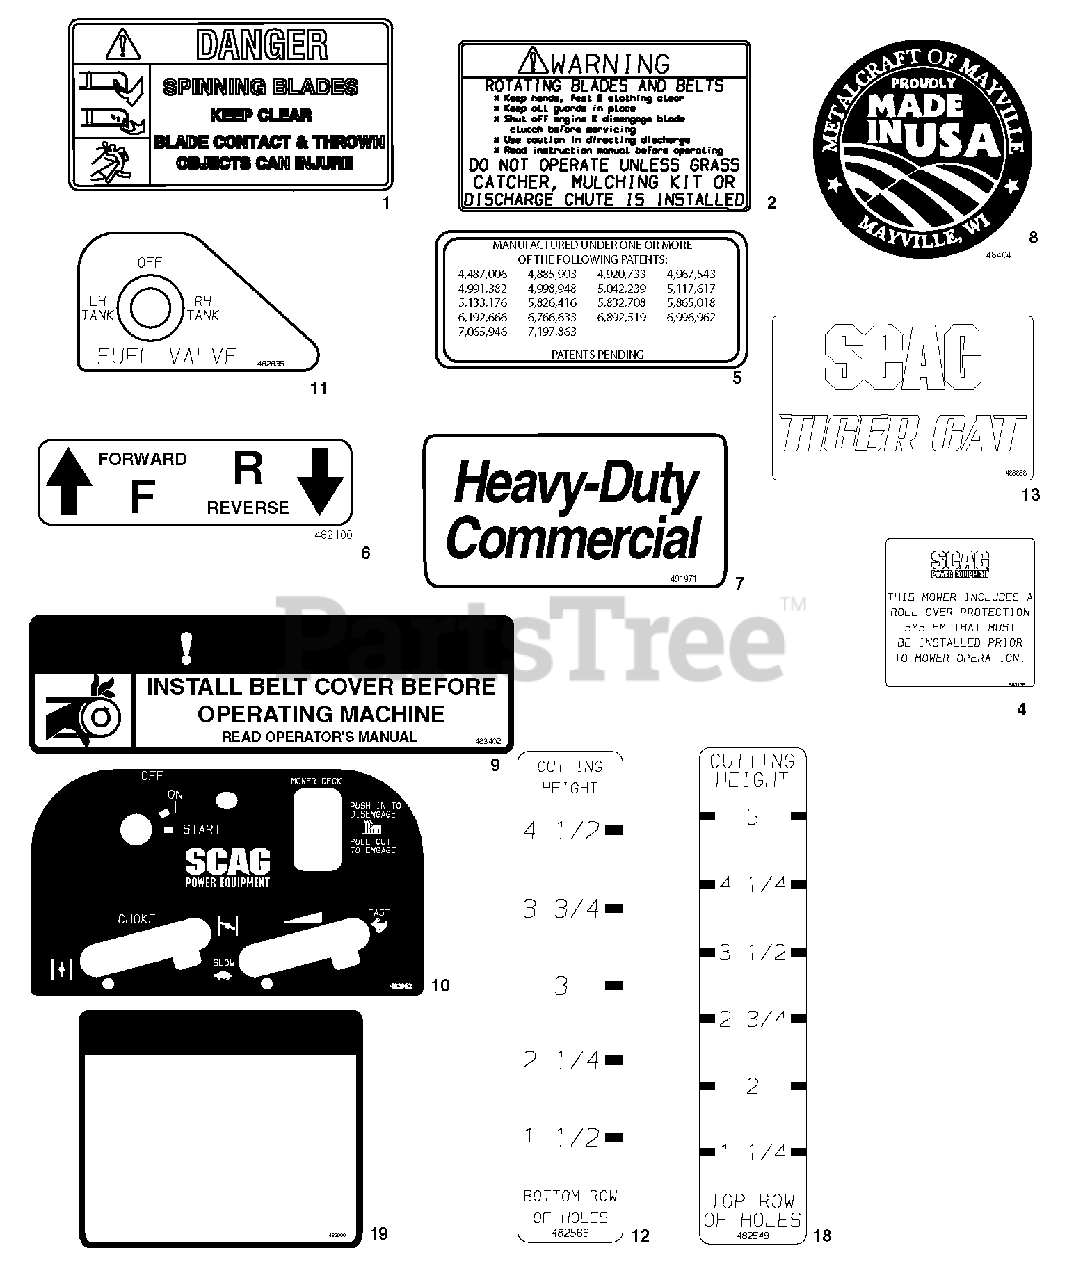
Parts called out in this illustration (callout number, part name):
1	Decal, Danger-Spinning Blades
2	Decal, Warning-Rotating Blades
4	Decal, ROPS
5	Decal, Patents
6	Decal, Traction Control
7	Decal, Heavy Duty Commercial
8	Decal, Metalcraft - Made in USA
9	Decal, Belt Cover
10	Decal, Instrument Panel
11	Decal, Fuel Valve Position
12	Decal, Cutting Height Bottom Row of Holes
13	Decal, Tiger Cat
14	Decal, Seat Support
15	Decal, Rear Bumper
16	Decal, Front Footplate
17	Decal, Discharge Chute
18	Decal, Cutting Height Top Row of Holes
19	Decal, Warning Spark Arrestor (California only)
